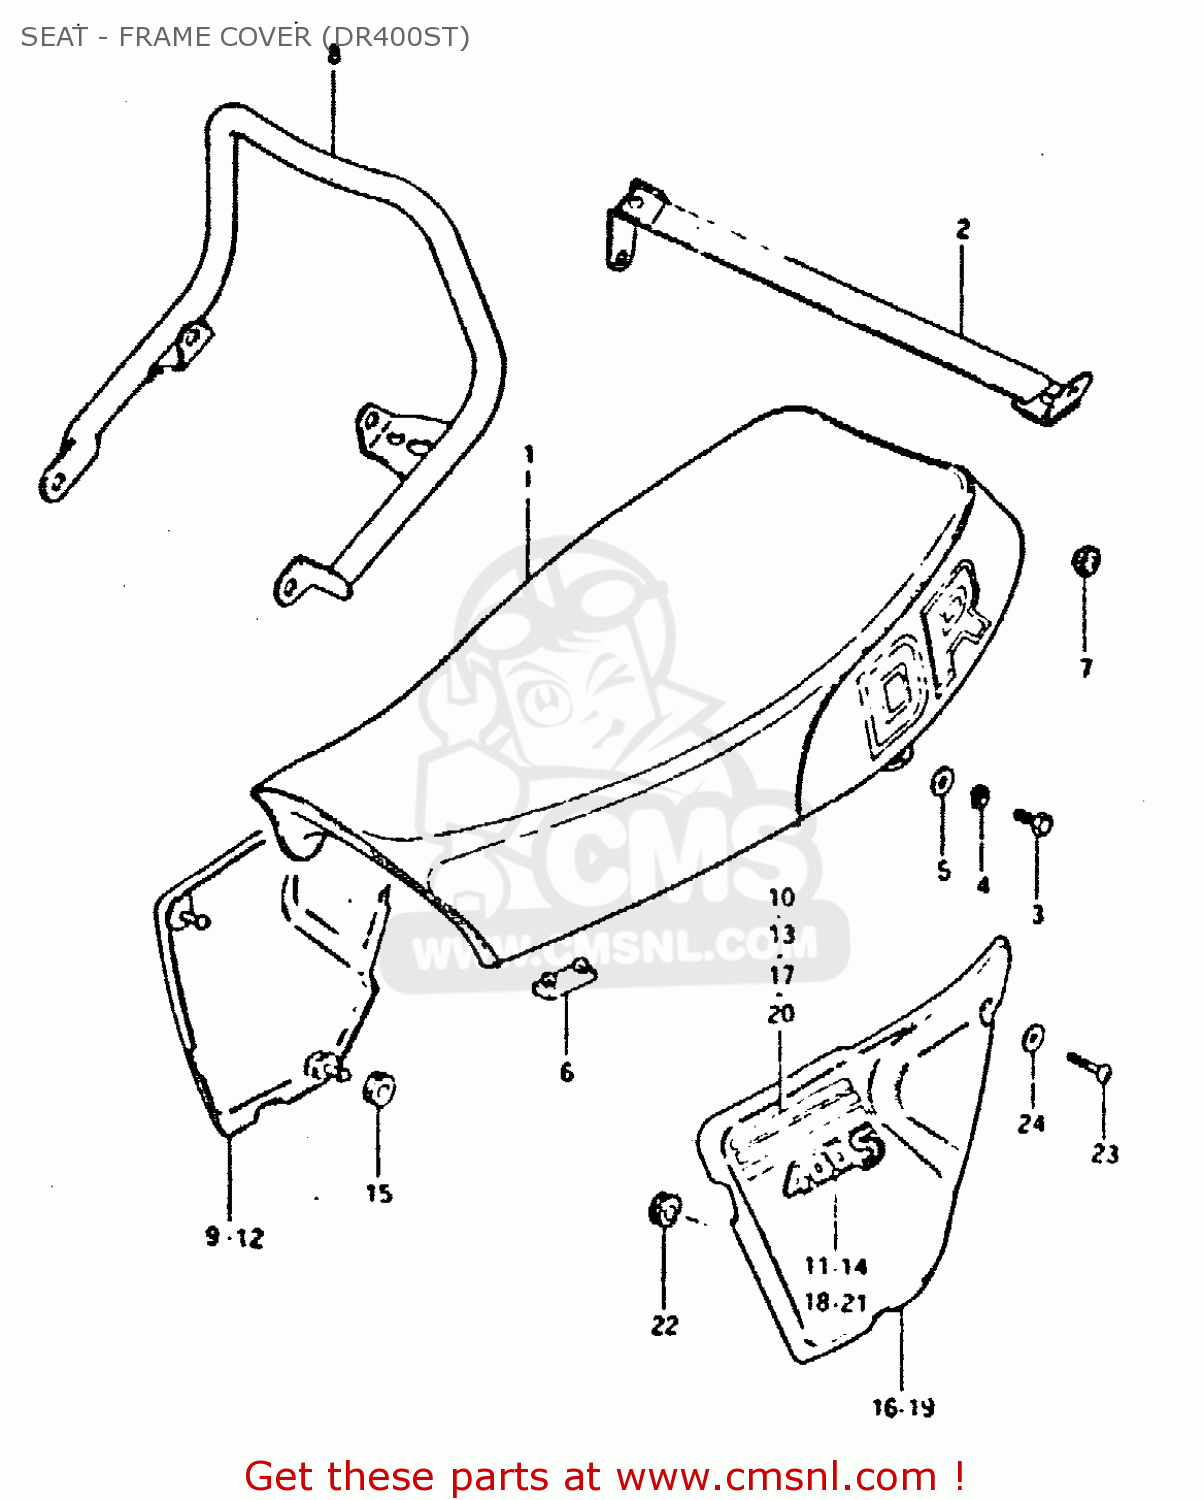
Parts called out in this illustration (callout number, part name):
1	SEAT ASSY (BLACK)
2	BAND, SEAT GRIP
3	BOLT
4	LOCK WASHER
5	WASHER
6	CUSHION
7	CUSHION
9	COVER,FRAME,RIGHT
10	TAPE,FRAME COVER,RIGHT STRIPE
11	EMBLEM, RH
12	COVER, FRAME RH (BLUE)
13	TAPE, RH
14	EMBLEM, RH
15	CUSHION
16	COVER,FRAME,LEFT
17	TAPE,FRAME COVER
18	EMBLEM, LH
19	COVER, FRAME LH (BLUE)
20	TAPE, LH
21	EMBLEM, LH
22	CUSHION
23	SCREW
24	WASHER
